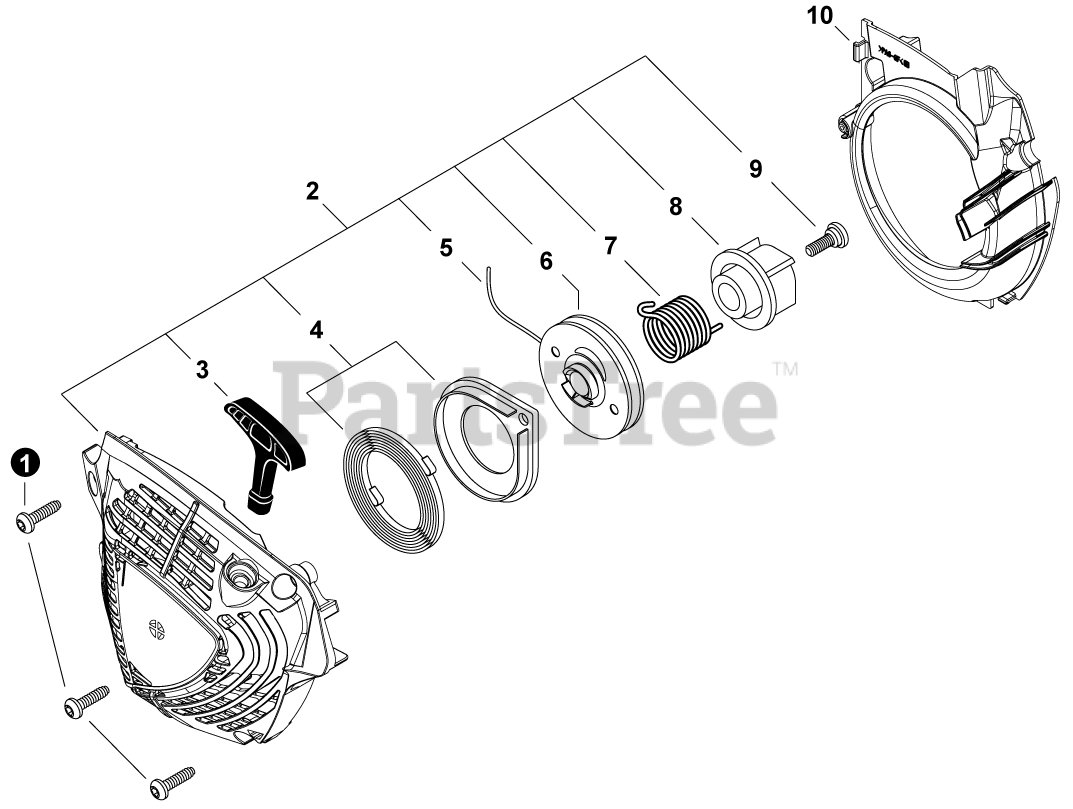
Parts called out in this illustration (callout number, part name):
1	BOLT, TORX 5x20
2	STARTER ASSY, RECOIL
3	GRIP, STARTER
4	SPRING KIT, RECOIL
5	ROPE, STARTER 3.5x900
6	REEL, ROPE
7	SPRING, TORSION
8	PAWL CATCHER
9	SCREW 5
10	COVER, FAN
